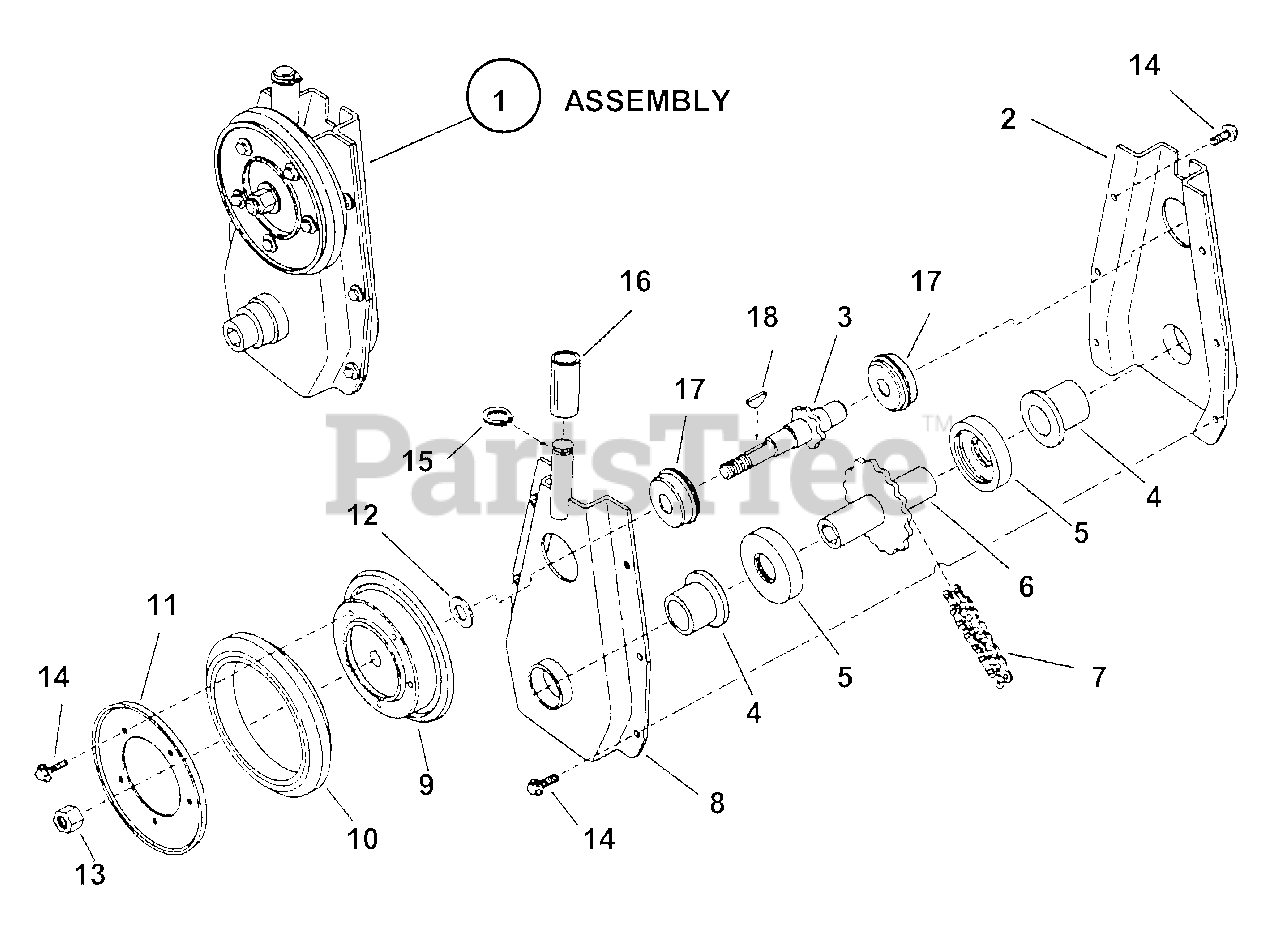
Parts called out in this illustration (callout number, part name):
1	ASSEMBLY, Chain Case
2	ASSEMBLY, Cover Sprocket
3	SHAFT & SPROCKET
4	BEARING
6	HUB & SPROCKET
7	CHAIN
8	ASSEMBLY, Sprocket Case
9	HUB, Driven Disc
10	RING, Driven (Rubber Disc)
11	PLATE
12	WASHER, 3/8" Flat
13	NUT, 3/8-24 Hex Top Lock, Grade C
14	SCREW, #10-24 x 1/2" Hex Washer Self-Tap (Torx)
15	RING, 1/2" External Retaining (Heavy Duty)
16	ROLLER
17	BEARING, Ball
18	KEY, 3/32 x 1/2" Woodruff
